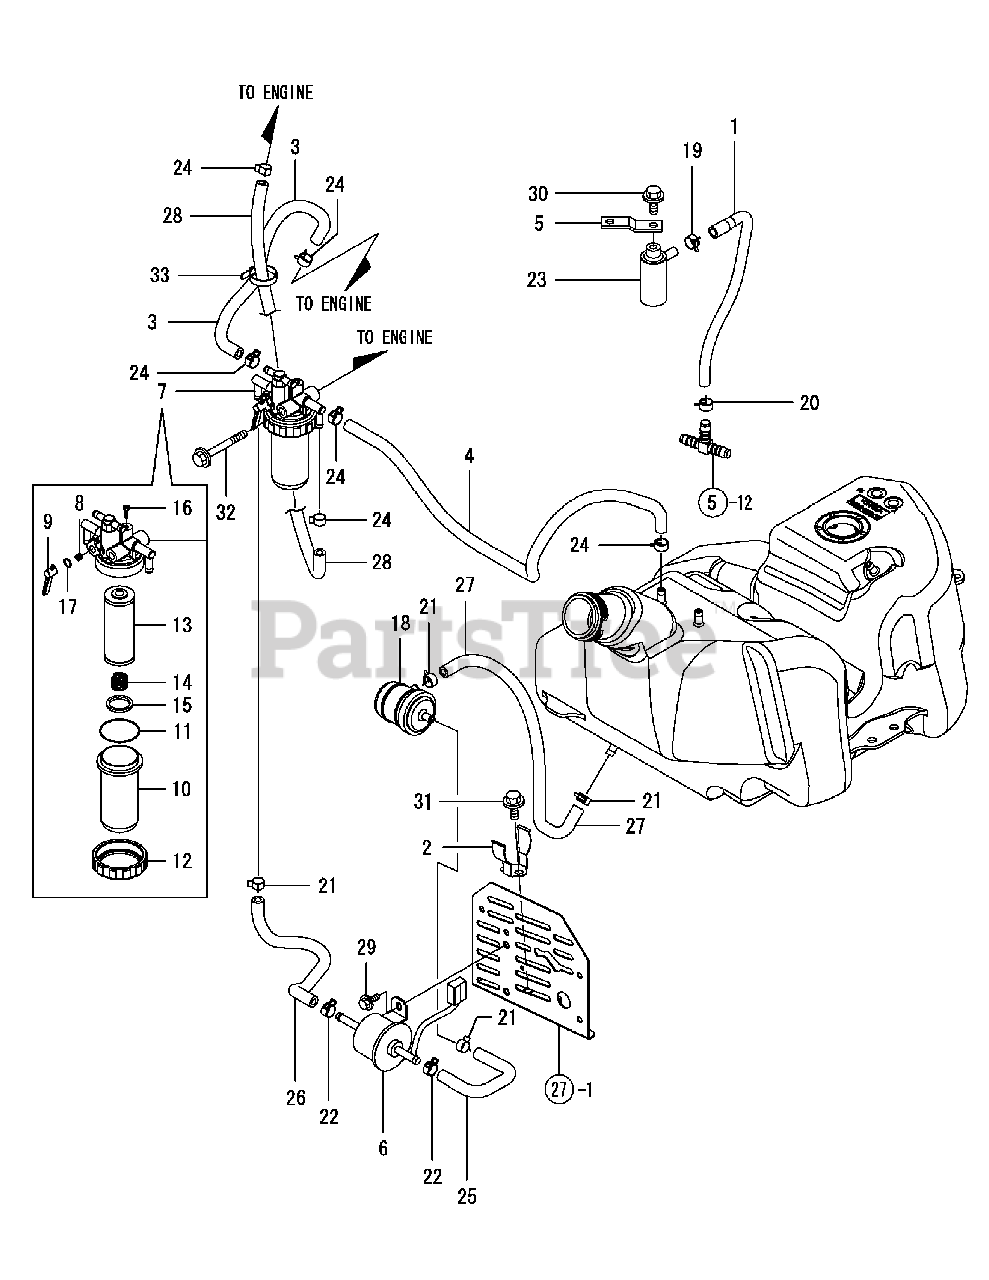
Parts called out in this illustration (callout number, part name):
1	HOSE, AIR VENT
5	SUPPORT, BREATHER
6	PUMP ASSY, FUEL FEED
7	FILTER ASSY, FUEL
12	RING, RETAINING
13	ELEMENT, STRAINER
14	SPRING, SCREEN
17	O-RING 1A P-10A
18	STRAINER,FUEL OIL(IN
25	HOSE 7.3X150,BRAIDED
26	HOSE, 7.3 X 260
27	HOSE 7.3,BRAIDED
28	FUEL PIPE 7.3X350
29	BOLT M 6X 16 PLATED
30	BOLT M 8X 12 PLATED
31	BOLT M 8X 12 PLATED
32	BOLT M 8X 60 PLATED
